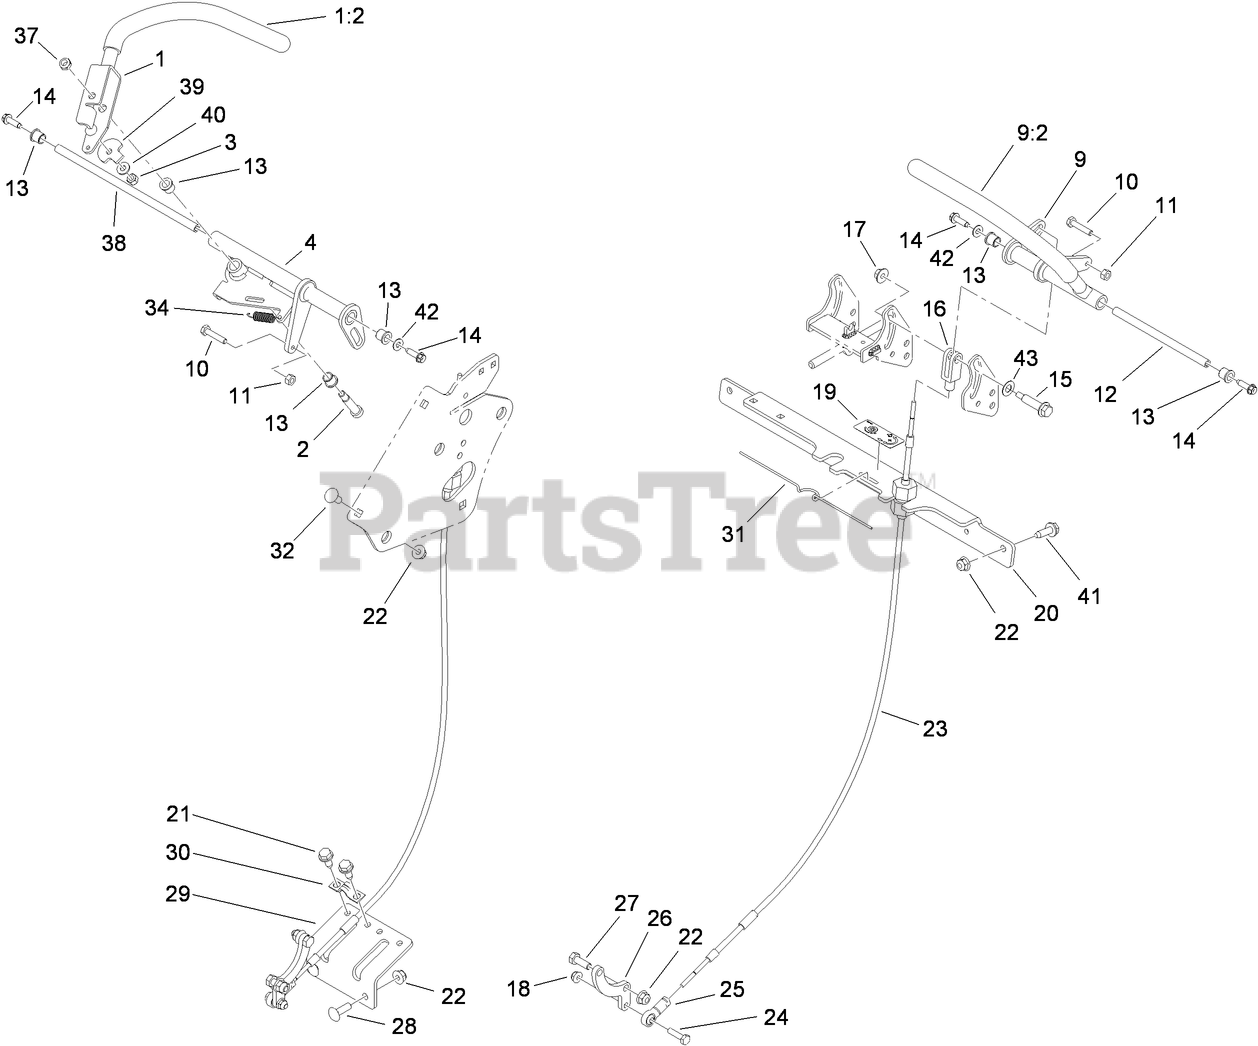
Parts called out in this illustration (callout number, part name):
1	LEVER-MOTION, RH
2	SCREW-HSH
3	NUT-LOCK, NI
4	RH MOTION CONTROL ASM
9	LH MOTION LEVER ASM
10	SCREW-HH
11	NUT-HEX
12	SHAFT-PIVOT, MOTION CONTROL
13	BEARING
14	SCREW-HH, TORX
15	SCREW-SHOULDER, HHF
16	YOKE-FEMALE
17	NUT-HF
18	NUT-HF
19	DECAL-TRACKING, HYDRO
20	BRACKET-CROSS
21	SCREW-HWHTF
22	NUT-HF, NI
23	CABLE ASM
24	SCREW-HH
25	ROD END-BALL JOINT
26	ARM-CONTROL, PUMP
27	SCREW-HH
28	BOLT-CARR
29	BRACKET-CLAMP, CABLE
30	CLAMP-CABLE
31	CLIP-SPRING
32	BOLT-CARR
34	SPRING-EXTENSION
37	NUT-LOCK, NI
38	SHAFT-PIVOT
39	CAM-LEVER
40	WASHER-FLAT
41	SCREW-HHF
42	WASHER-FLAT
43	WASHER-THRUST
